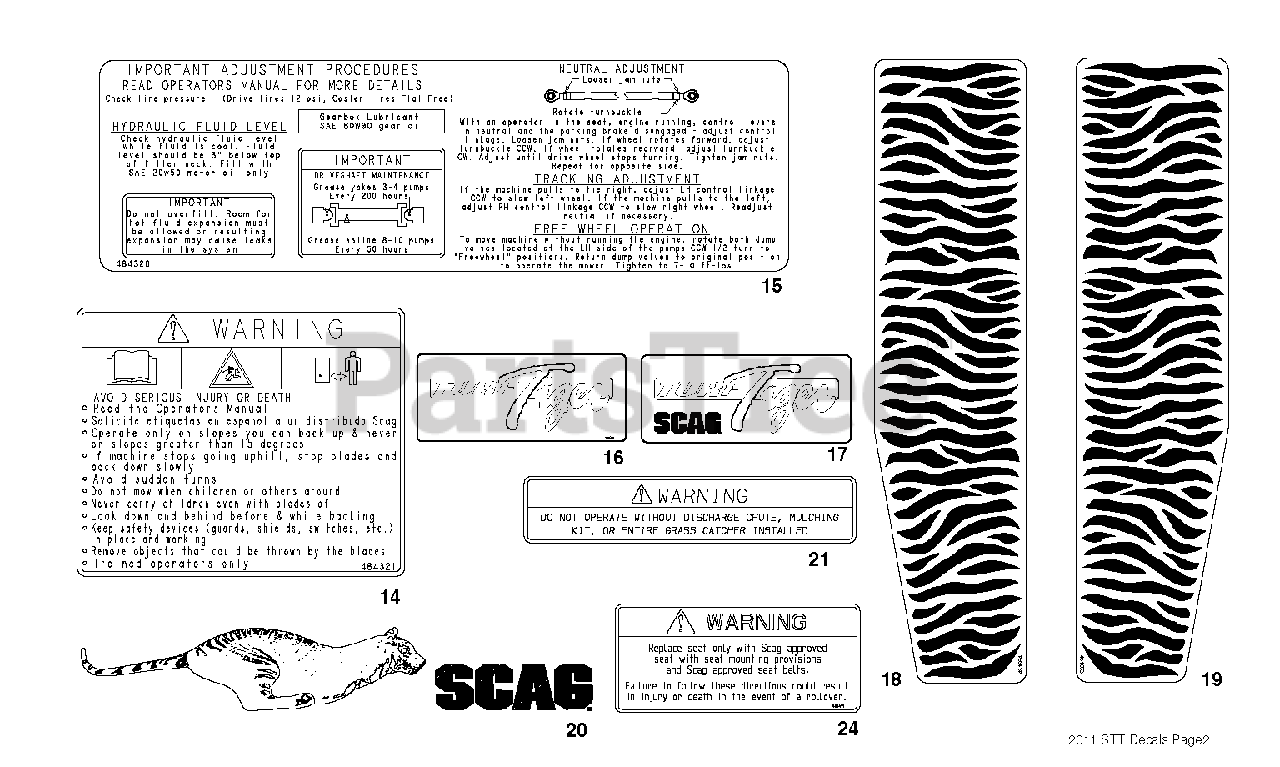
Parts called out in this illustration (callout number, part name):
14	Decal, Fuel Tank Warning
15	Decal, STT Adjustments
16	Decal, Turf Tiger
17	Decal, Turf Tiger
18	Decal, Stripes-RH
19	Decal, Stripes-LH
20	Decal, Tiger
21	Decal, Warning
24	Decal, ROPS
